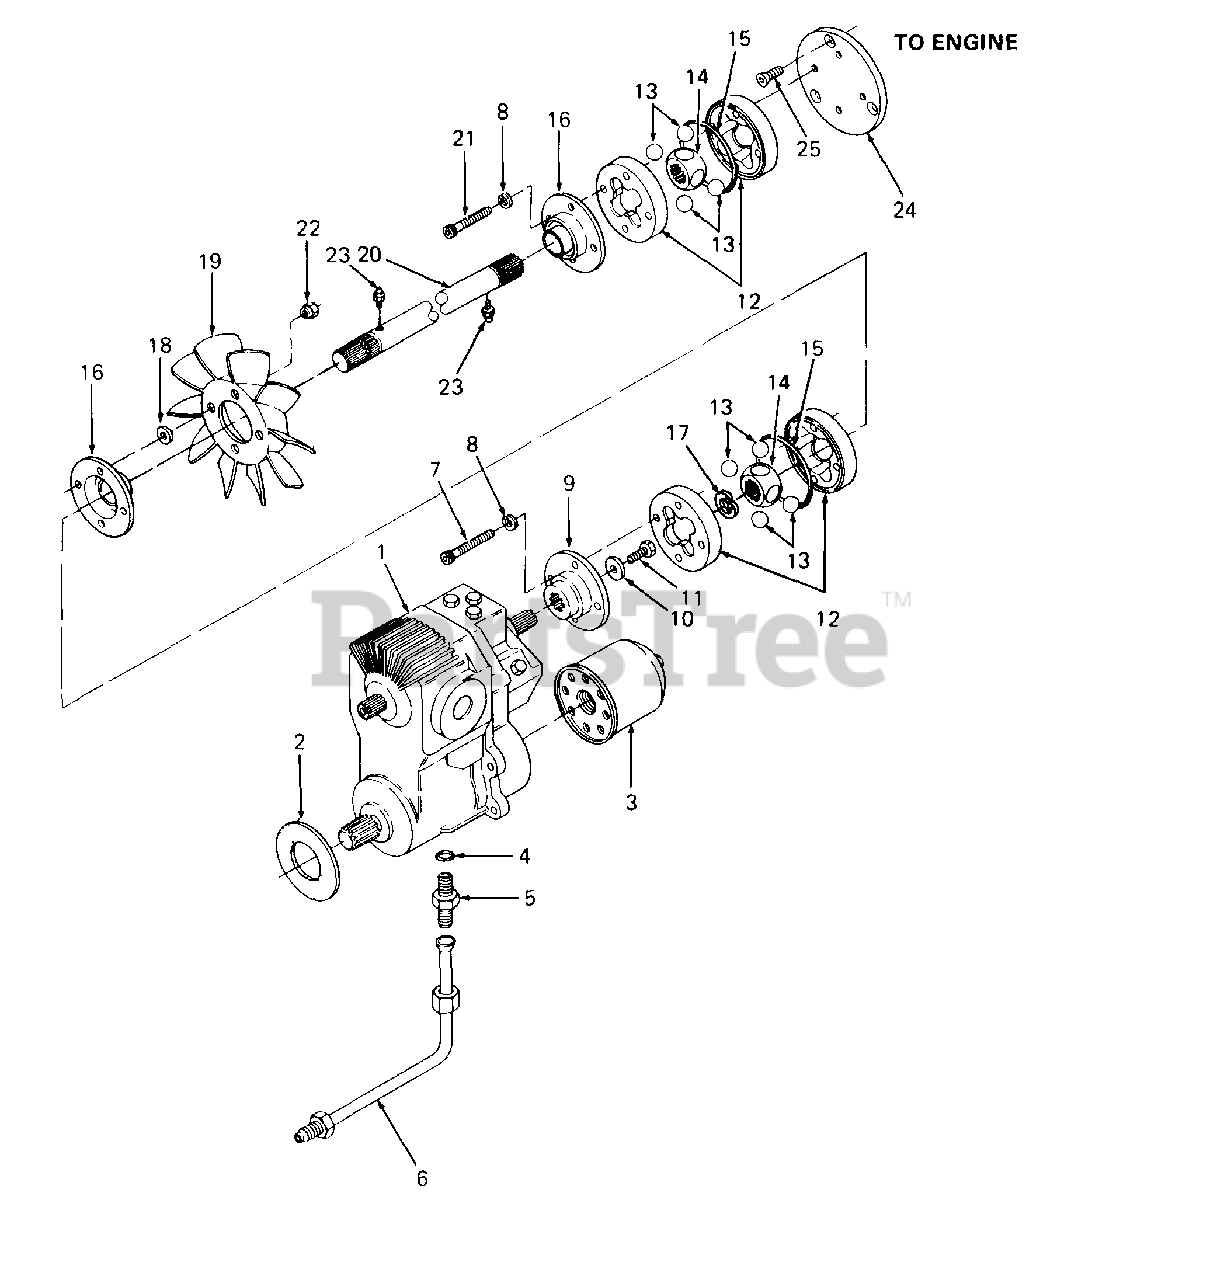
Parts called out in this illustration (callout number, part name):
1	Pump, Hydrostatic
2	Gasket, Front
3	Filter, Oil
4	O-Ring, 5/8 OD Tube
5	Connector, 37 Degree
6	Tube Assy
7	Screw, Socket Hd Cap, 1/4-20 X 2.0 Lg
8	Washer, Lock, 1/4
9	Adapter, Pump
10	Washer, Bell, .265 X .75 X .062 Thk
11	Screw, Hex Patch, 1/4-20 X 1.0 Lg GR5
12	Coupling, Drive w/O-Ring Groove
13	Ball, Steel, 5/8 Dia Chrome
14	Hub, Drive
15	O-Ring, 2.489 X .070
16	Boot, Coupling CV-Joint Grease
17	Ring, Snap
18	Washer, Flat, .25 X .62 X .052 Thk
19	Fan, 10 Blade Hydro
20	Shaft, Drive, 22.88 Lg
21	Screw, Hex Patch, 1/4-20 X 1.62 Lg GR5
22	Nut, Fan, 1/4-20
23	Fitting, Grease
24	Plate, Coupling Adapter
25	Screw, Flat Hd Cntsnk w/Patch, M8 X 16 Lg GR5
